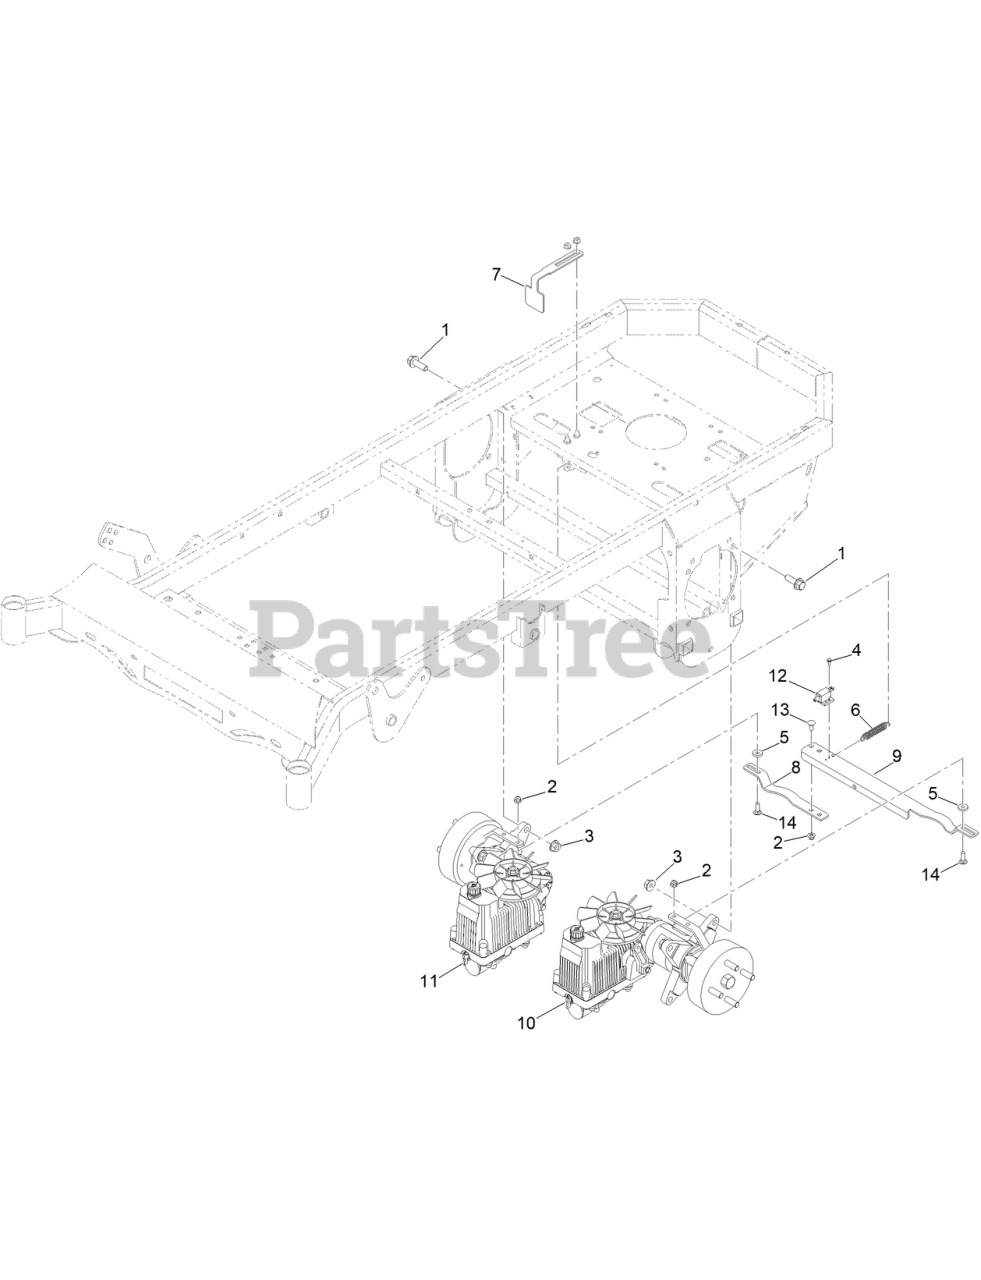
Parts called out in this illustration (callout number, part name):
1	SCREW-HHF
2	NUT-HF, NI
3	NUT-HHF
4	8-32 X 1/2 IND. HWH SLOT TYPE F TCS ZINC
5	.312 ID X .875OD X .1875 THK F/W NYL
6	MWR BRAKE PEDAL RELEASE SPRING
7	STAND TRANSM BRAKE INTERLOCK BRKT BLACK
8	MWR PARK BRAKE BRKT RT PAINTED
9	MWR PARK BRAKE BRKT LT PAINTD BLACK
10	HTE10 LT SIDE HYDROST TRANSM FOR RZ HUB
11	HTE10 RT SIDE HYDROST TRANSM FOR RZ HUB
12	NO PLUNGER LIMIT SWITCH
13	BOLT-CARR
14	BOLT-CARR
